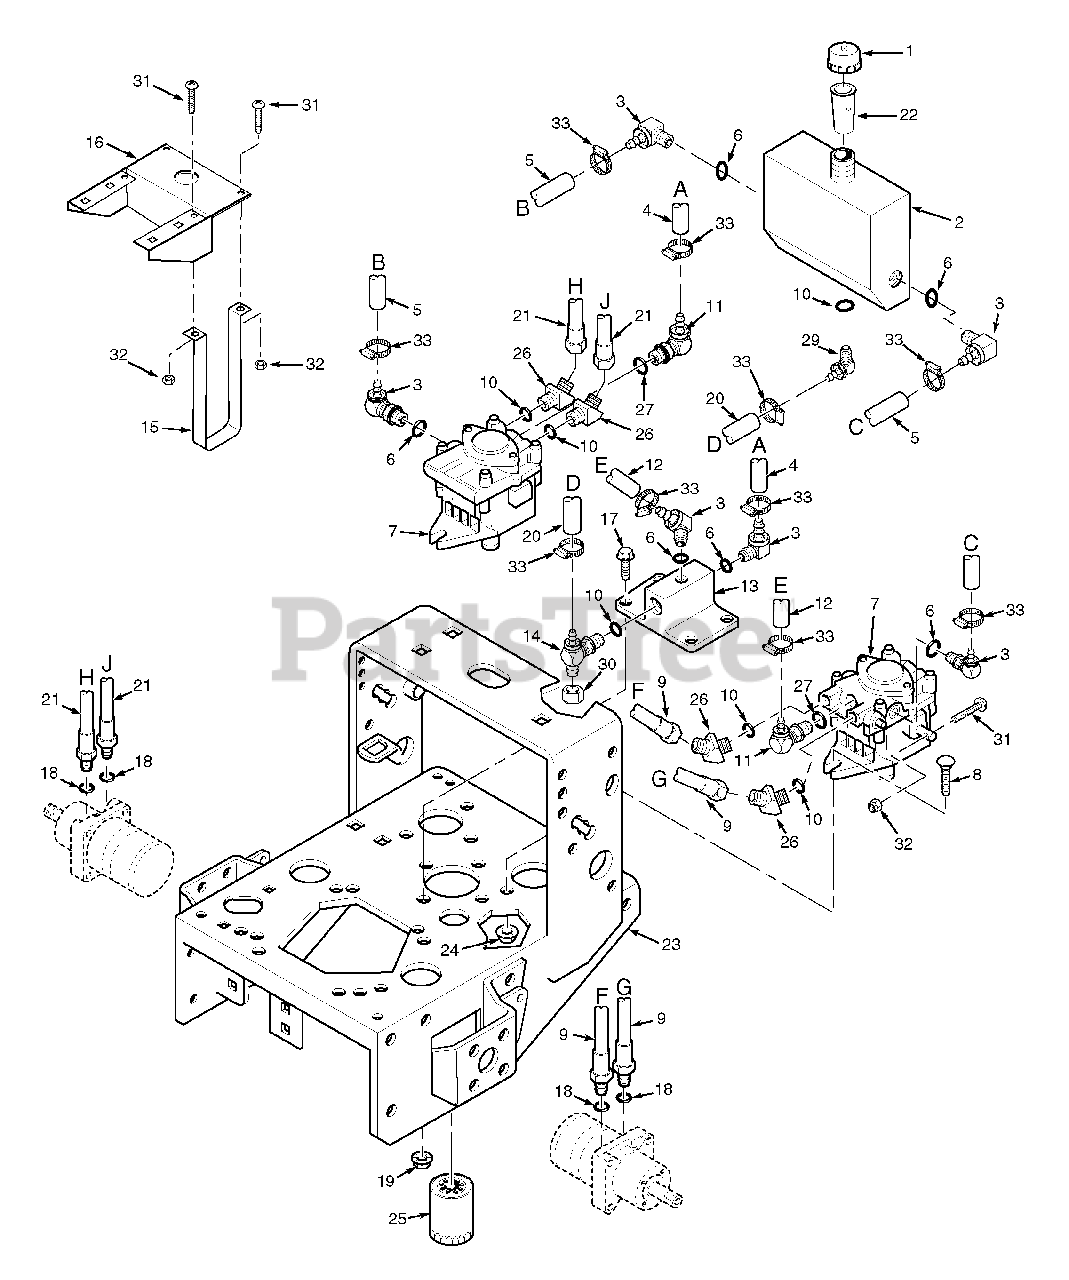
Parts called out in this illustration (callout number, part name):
1	Cap, Oil Reservoir
2	Oil Reservoir (With Fittings)
3	Elbow, 9/16" O-Ring x 3/8" Hose
4	Hose, 3/8" ID - 16" Long
5	Hose, 3/8" ID - 7" Long
6	O-Ring
7	Pump, Hydro-Gear BDP-10L117
8	Bolt, Carriage, 3/8-16 x 1-1/4"
9	Hose, Pump to Wheel Motor
10	O-Ring
11	Elbow, 7/16" O-Ring x 3/8" Hose
12	Hose, 3/8" ID - 10-1/4" Long
13	Oil Filter Base
14	Tee, 3/8" O-Ring x JIC x 1/2" Hose
15	Strap, Hydraulic Tank
16	Bracket, Hydraulic Tank
17	Capscrew, 5/16-18 x 3/4" Serr. Flange
18	O-Ring
19	Nut, 5/16-18 Serr. Flange
20	Hose, Formed 1/2" ID
21	Hose, Pump to Wheel Motor
22	Tube, Filler Neck
23	Engine Deck (16" Wide) W/Decals - Small Frame
24	Nut, 3/8-16 Serr. Flange
25	Oil Filter
26	Elbow, 45 Deg.-3/4-16 JIC Male x Male 3/4-16 O-Ring
27	O-Ring
28	Coupling, 3/8" Pipe to 1/2" Push-on
29	Elbow, 3/4-16 O-Ring x 1/2" Hose
30	Cap, 3/4-16
31	Screw, 1/4-20 x 2" Round Head Phillips
32	Nut, 1/4-20
33	Clamp, .87" max dia.
